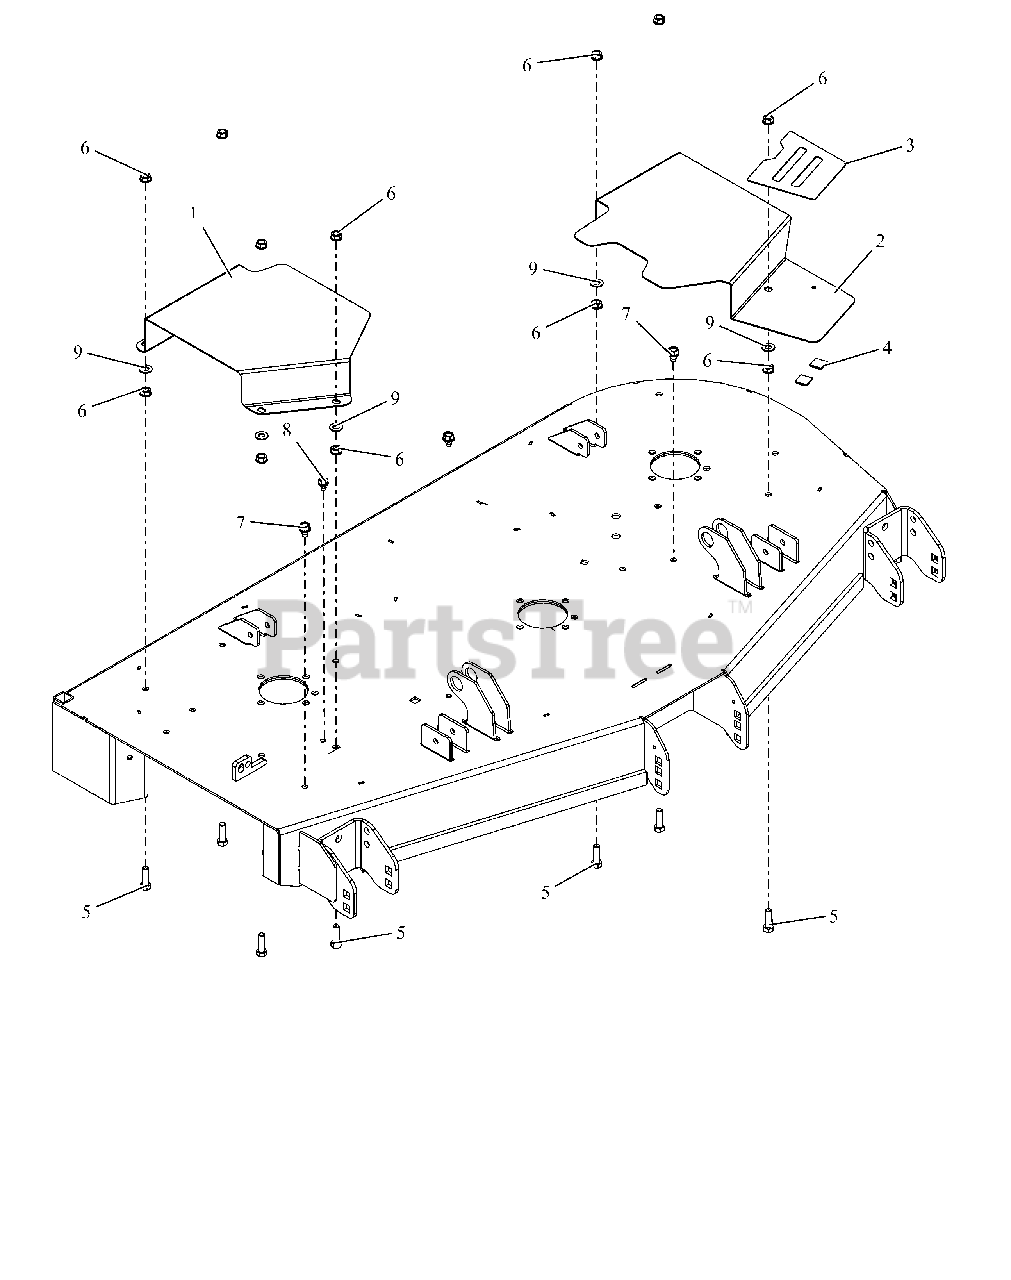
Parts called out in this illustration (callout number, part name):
1	COVER, BELT 52" & 60" RIGHT
2	COVER, BELT 52" LEFT
3	GRIP, TAPE 52-60 BELT COVER
5	BLT, HEX .38-16X1.25 G5 ZCC
6	NUT, SPNLK-FLG .38-16 G5 ZCC
7	SCR,TAP .375-16X.50 HWH TR ZCC
8	SCR,TAP .312-18X.50 HWH TR ZCC
9	WSHR,FLT .406X.812X.065 ZCC
